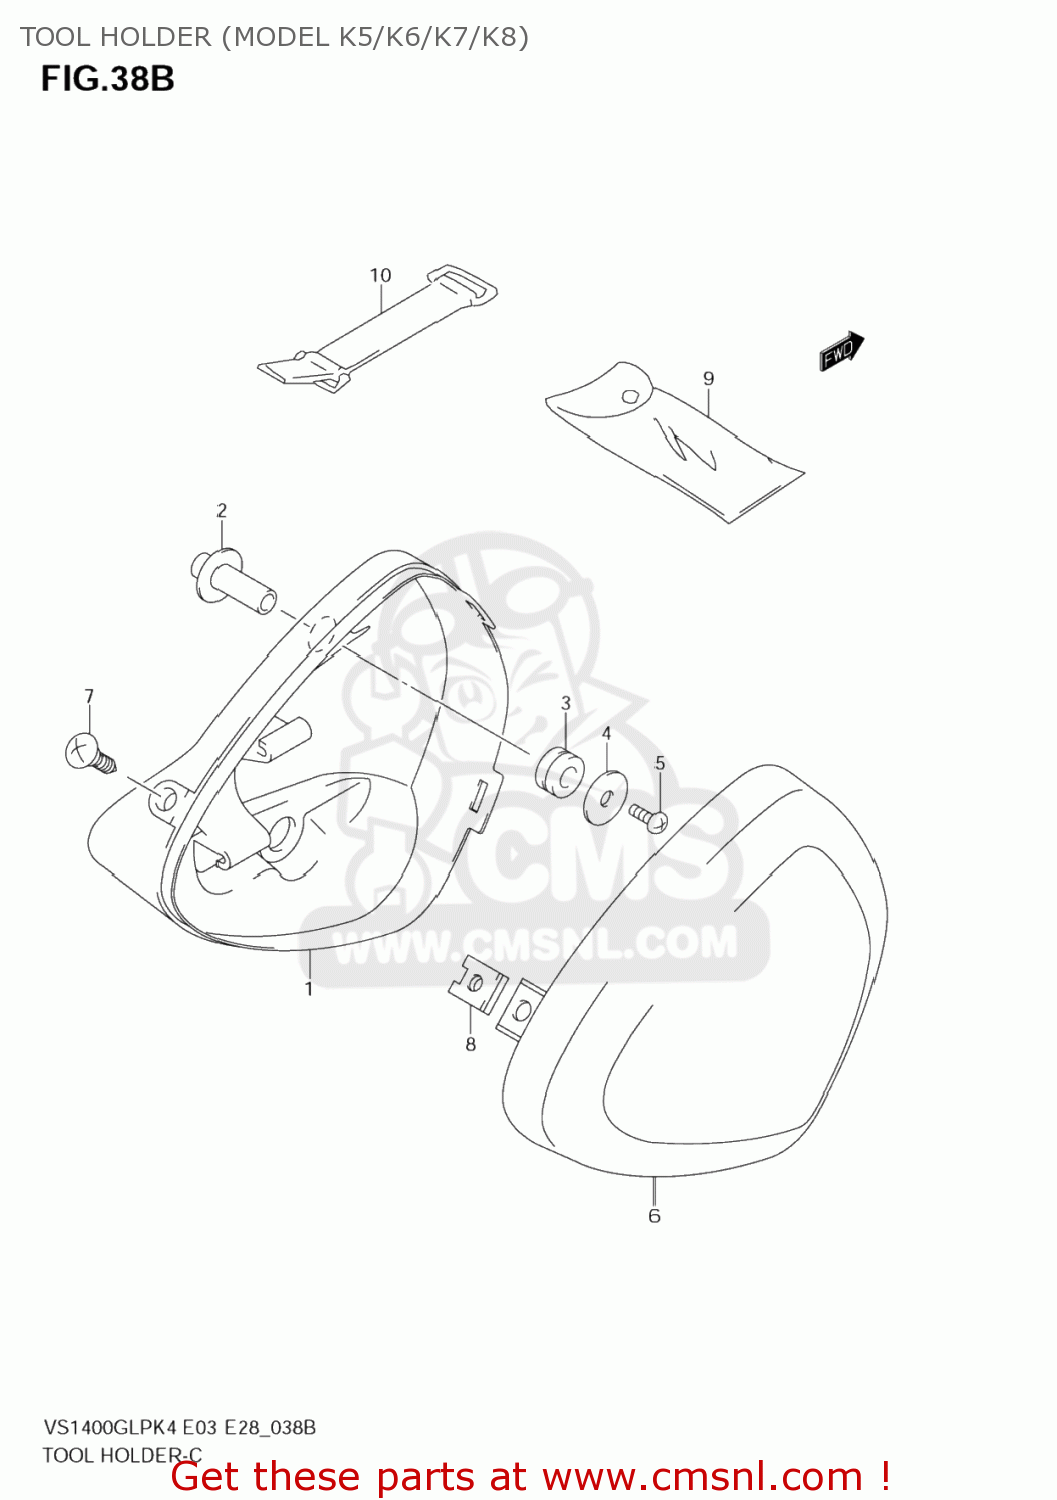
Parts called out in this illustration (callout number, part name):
1	BOX, LUGGAGE V
2	SPACER,TOOL HOLDER
3	CUSHION
4	WASHER(6.5X22X1.6)
5	SCREW
6	CAP,TOOL HOLDER
7	SCREW(6X23)
8	NUT
9	TOOL ASSY
10	BAND
